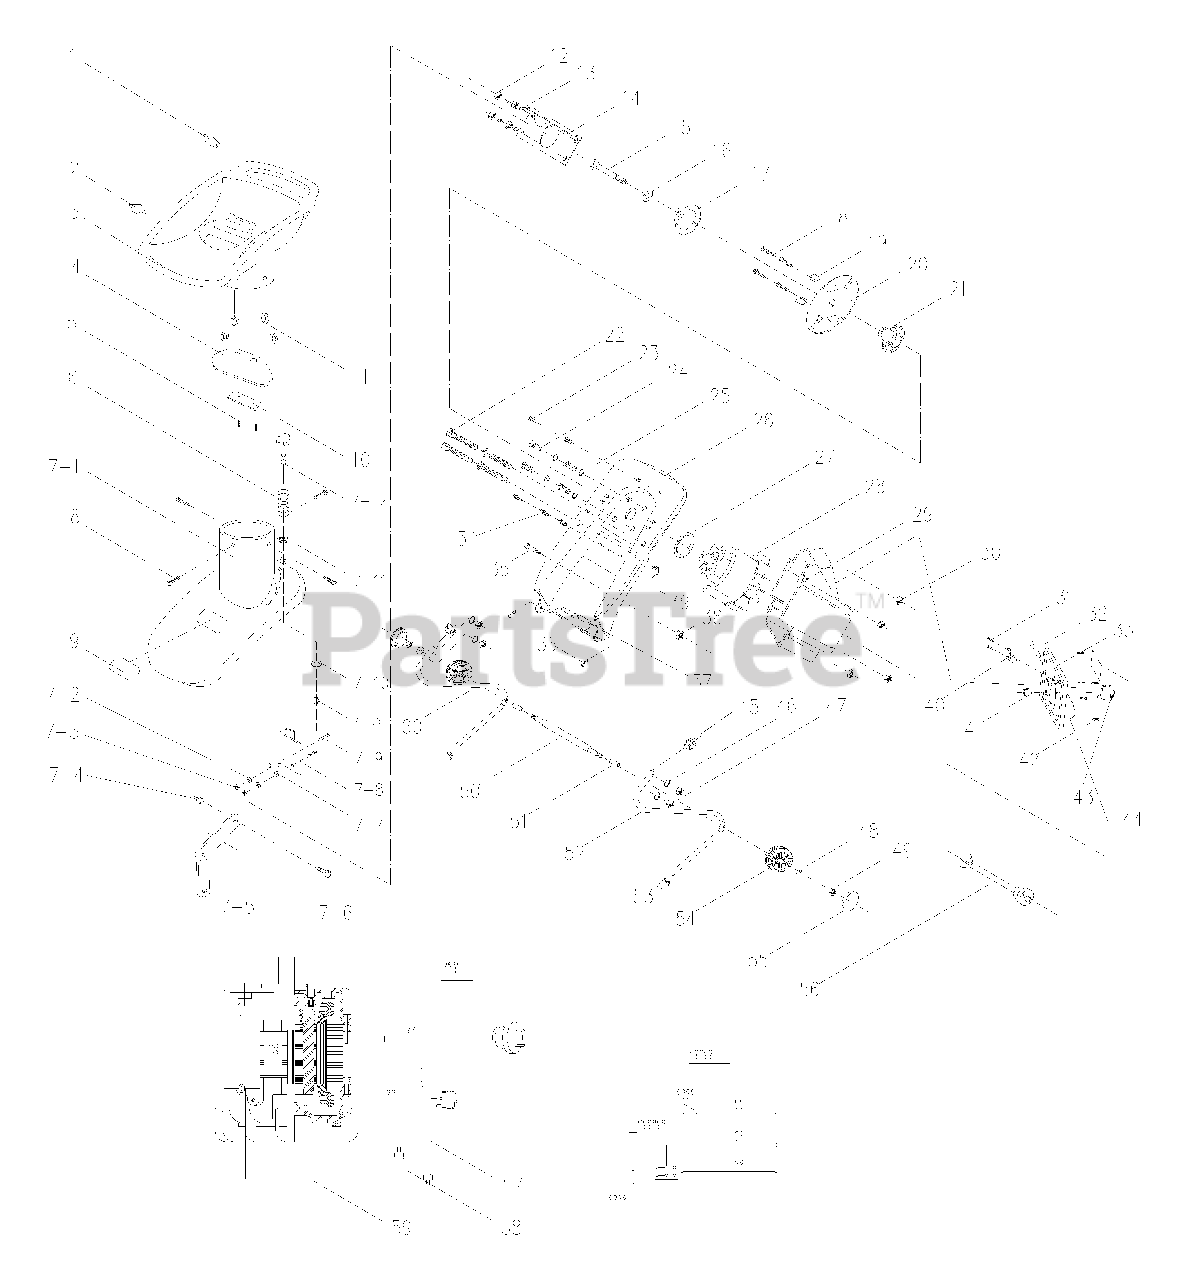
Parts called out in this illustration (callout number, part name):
1	LABEL (BRANCH)
2	LABEL (LEAVES)
3	TOP HOPPER
4	DUST PLATE
7	HOUSING ASS'Y
7-4	C RING
7-11	SPRING SEAT
10	PRESSURE PLATE
13	SPRING WASHER
14	FIXED SEAT
17	FIXED CAP
20	CUTTER HEAD
25	SPRING WASHER
26	SUPPORTING PLATE
27	RUBBER WASHER
29	MOTOR CASING
32	CORD GUARD
33	SWITCHBOARD
35	SCREW ARBOR
40	STRAIN RELIEF
41	PROTECTIVE
45	RUBBER WASHER
50	CONNECTING ROD
52	SUPPORT (L)
53	RUBBER MAT
55	WHEEL CAP
56	POWER CORD
60	SUPPORT (R)
